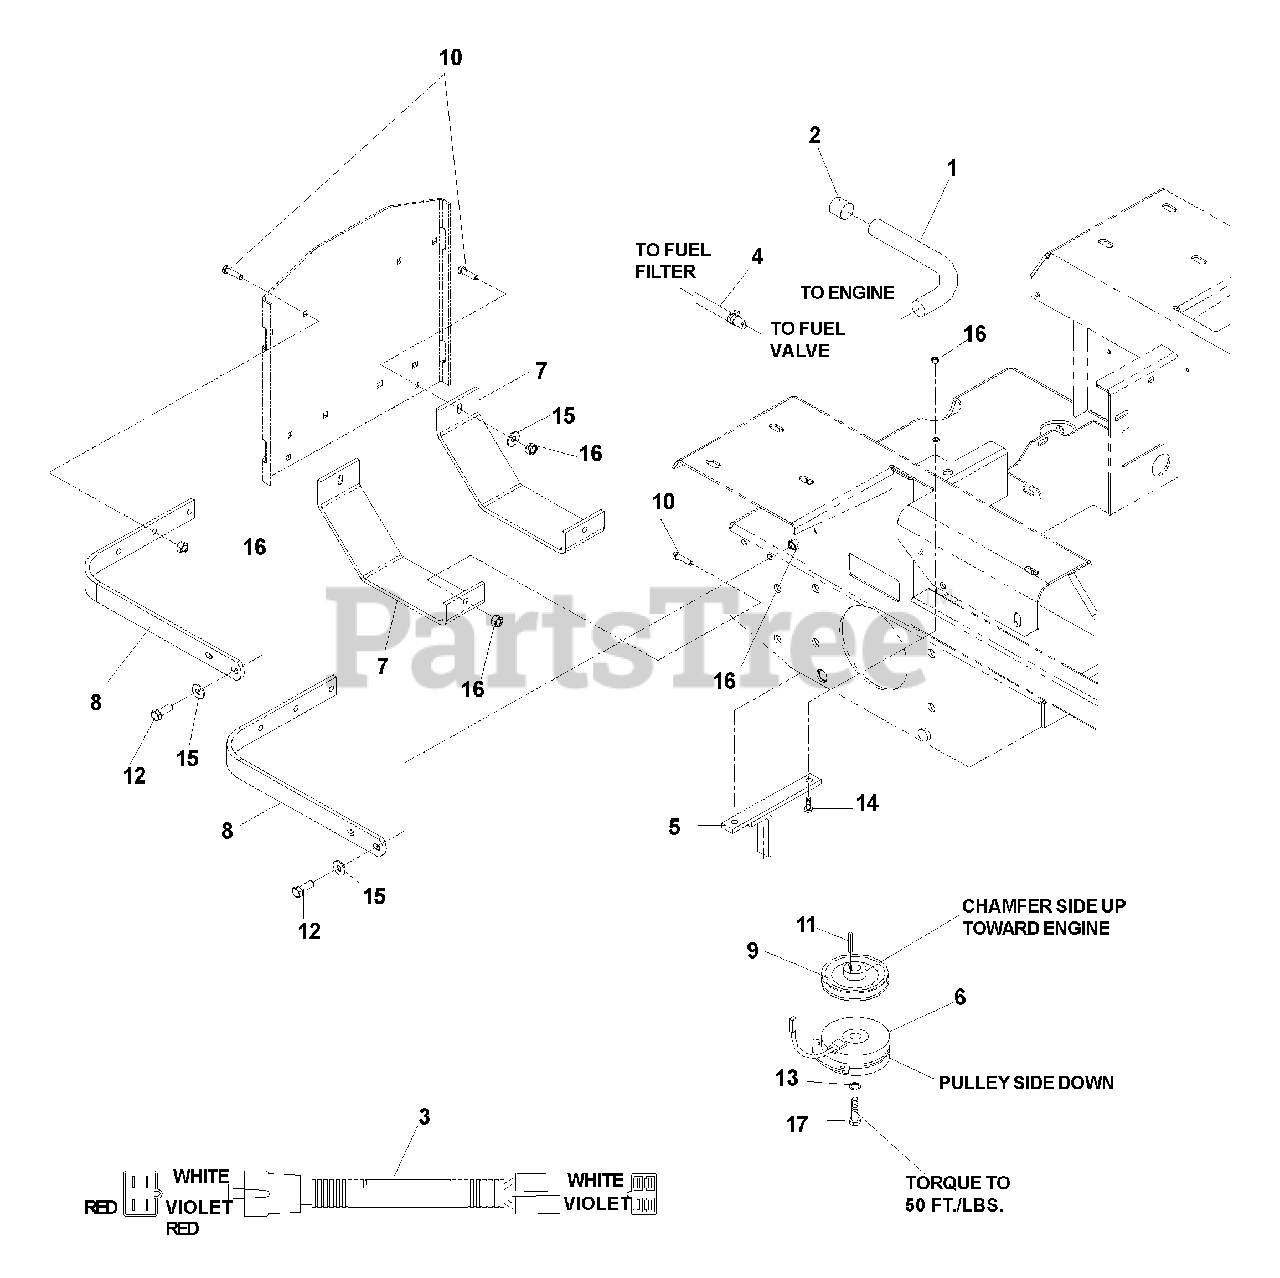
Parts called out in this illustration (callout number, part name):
1	HOSE-DRAIN
3	PIGTAIL, KOHLER
4	FUEL LINE, 13
5	CLUTCH TIE DOWN
7	SKID PLATE
10	RHSNB, 5/16-18 X 1, GR5
11	KEY, 1/4 SQ X 1 1/4
12	HCS, 5/16-18 X 1, GR5
13	LOCKWASHER, 7/16
14	HCS, 5/16-18 X 1 3/4, GR5
15	WASHER, 5/16
16	NUT, 5/16-18, NYLOC
17	HCS, 7/16-20 X 2 1/2, GR5
